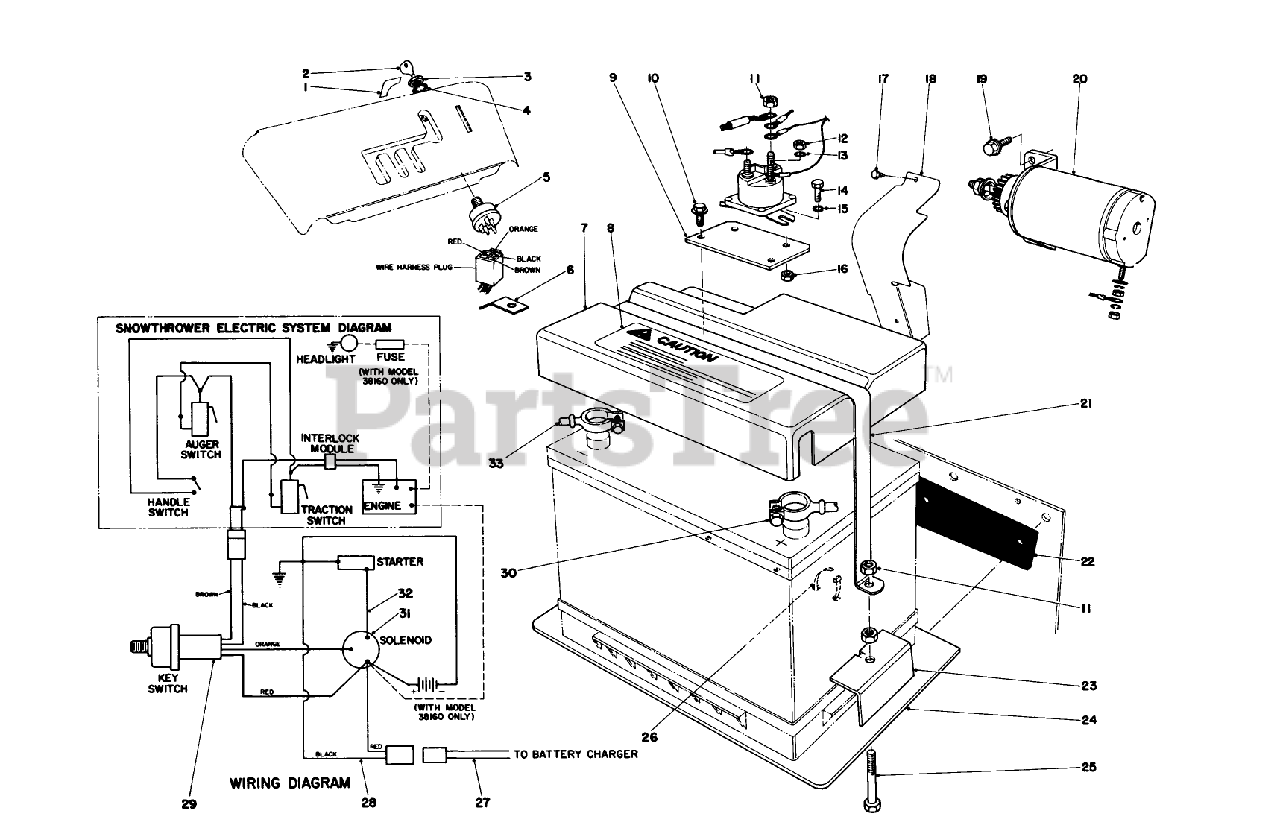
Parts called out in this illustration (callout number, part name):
3	NUT-HH
4	WASHER-LOCK
10	SCREW-HWH
11	NUT-HEX
12	NUT-HEX
13	WASHER-LOCK, INT
14	SCREW-HH
15	7 Lock washer
16	19 Nut
18	BRIGGS 280265
19	5/16-18X3/4 HX HD SEM
20	Starter Motor Pinion Assy.
25	SCREW-HH
26	TIE-CABLE
27	MALE WIRE ASM
29	Wire Harness
30	BATT-SOLENOID CABLE
31	SOLENOID
